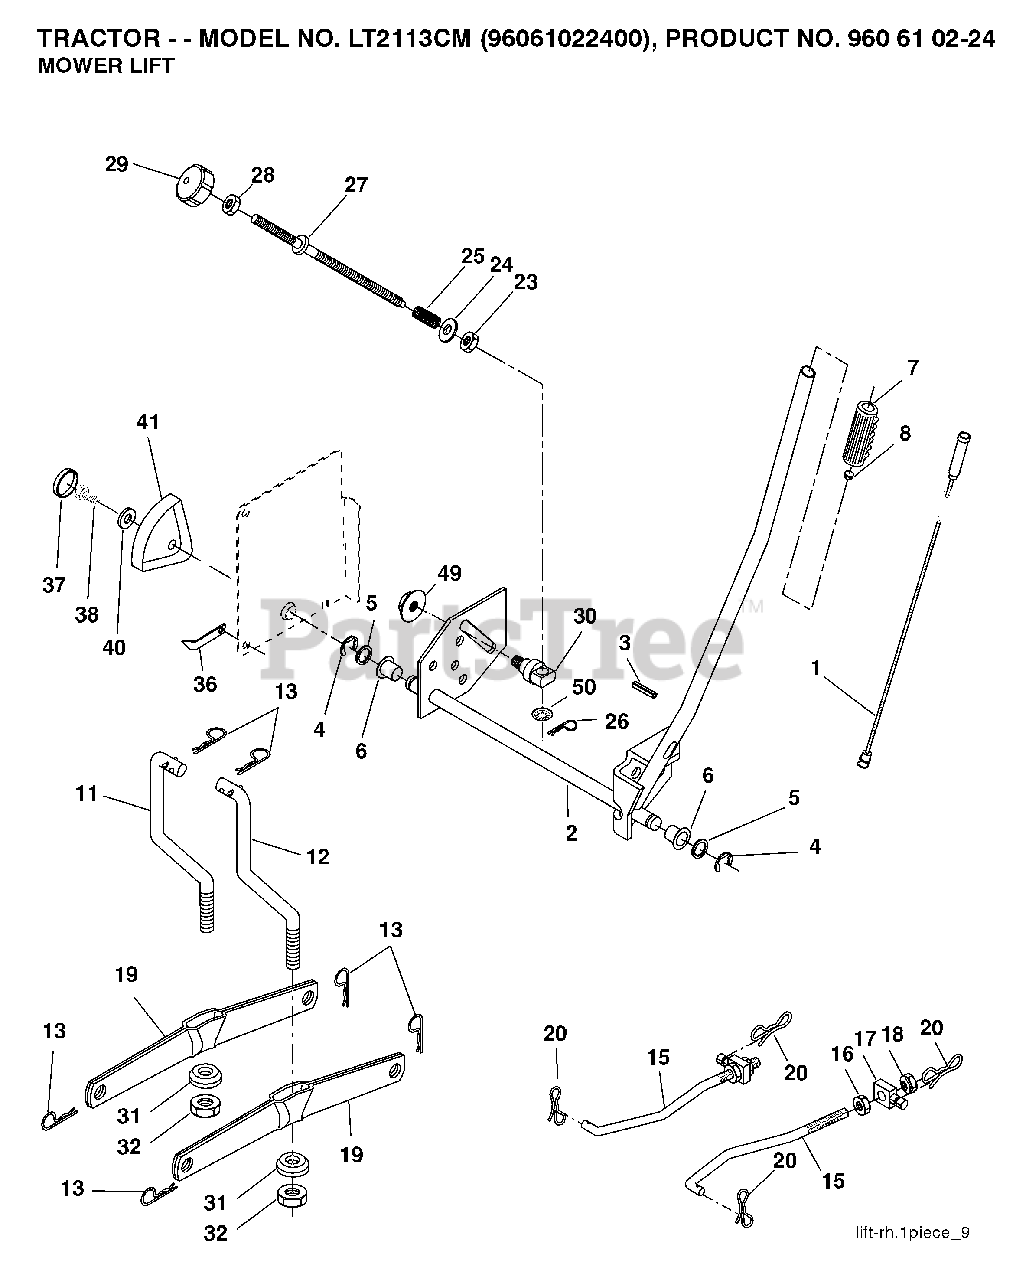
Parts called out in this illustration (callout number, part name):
4	RETAINING RING LT
6	BEARING.NYLON
7	GRIP HANDLE
8	PLUNGER BUT KIT
11	LINK
12	LINK
13	RETAINER-SPRNG RB
15	LINK.SUSPENSION.FRONT
16	NUT
18	NUT
19	ARM.REAR.SUSPENSION
20	PIN.COTTER.7/16.BOW TI
25	SPRING**
26	RETAINER CLIP
27	ROD ADJ LIFT
28	NUT
29	KNOB INF 3/8-16
31	BEARING.PIVOT.LIFT
32	NUT CROWNLOCK 3/8-24
36	POINTER, HEIGHT INDICATOR
37	PLUG,HOLE
38	SCREW 5/16-18X1
41	HEIGHT INDICATOR
49	NUT
50	NUT PUSH M
